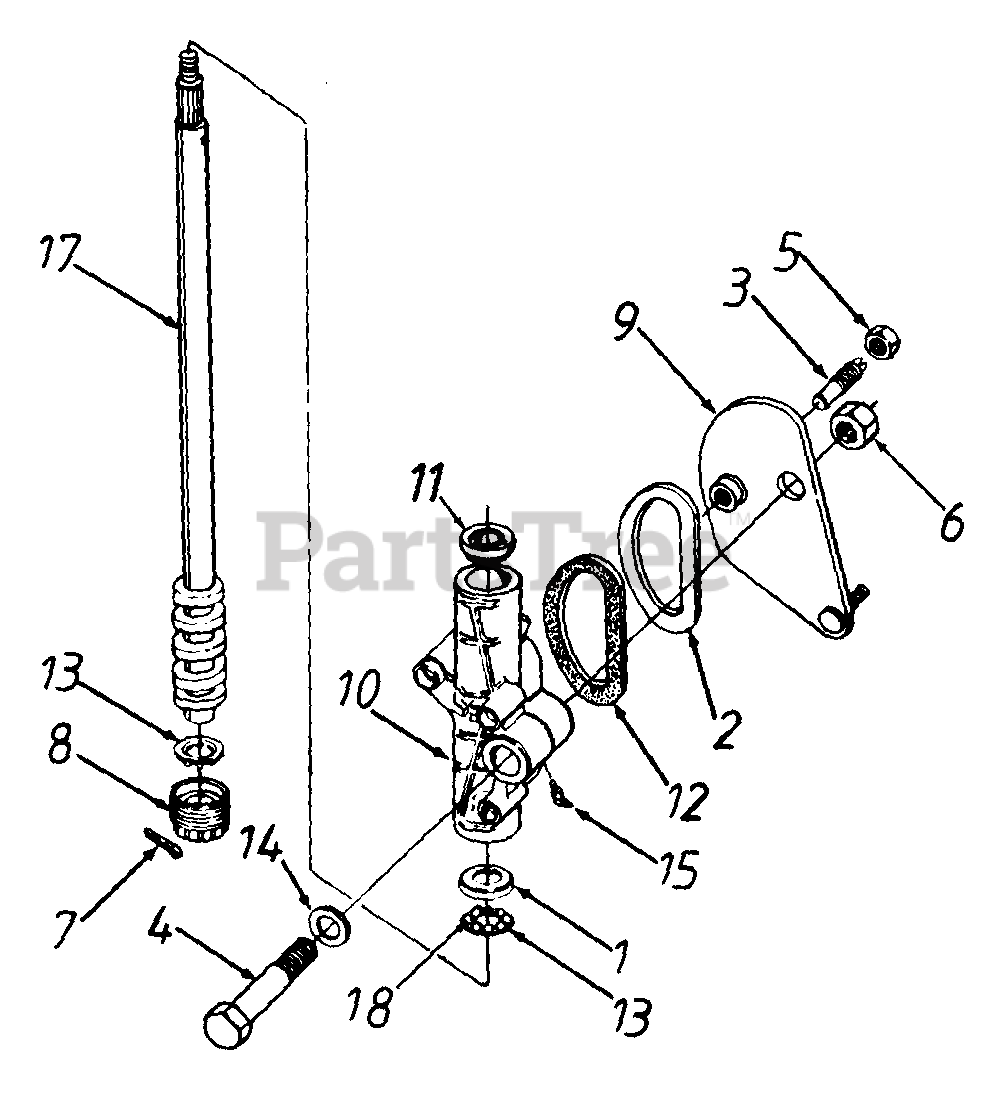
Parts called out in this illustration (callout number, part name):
1	Bearing Cup
2	Seal Retainer
3	Cam Follower
5	Hex Jam Nut 9/16-18 Thd.
6	Hex Crown L-Nut 5/8-18 Thd.
7	Cotter Pin 1/8" Dia.
8	Adjustment Plug Ass'y.
9	Steering Arm Ass'y.
10	Steering Hsg. Bushing Ass'y.
12	Seal
13	Ball Retainer
14	Fl-Wash. .781" I.D. x 1.25" O.D.
15	Grease Fitting
17	Steering Shaft Ass'y.
18	Ball Bearing
